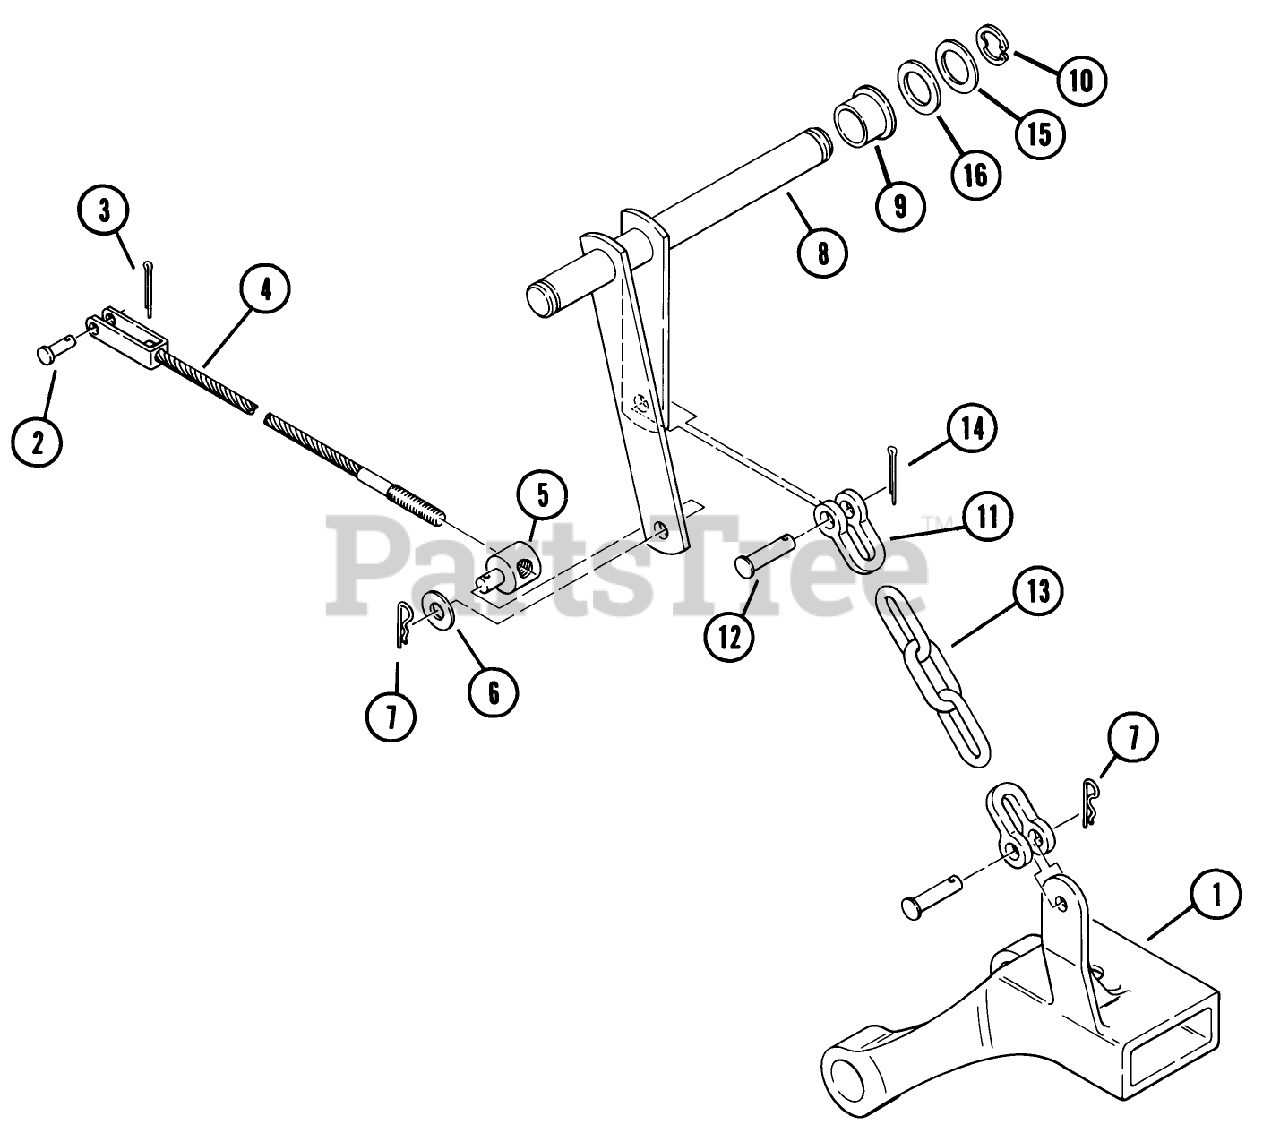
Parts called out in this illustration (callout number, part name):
4	ASSY-LIFT CABLE
5	TRUNNION-CLUTCH ROD
7	Hairpin
9	BUSHING
10	E-RING
15	WASHER
16	WASHER-SHIM
